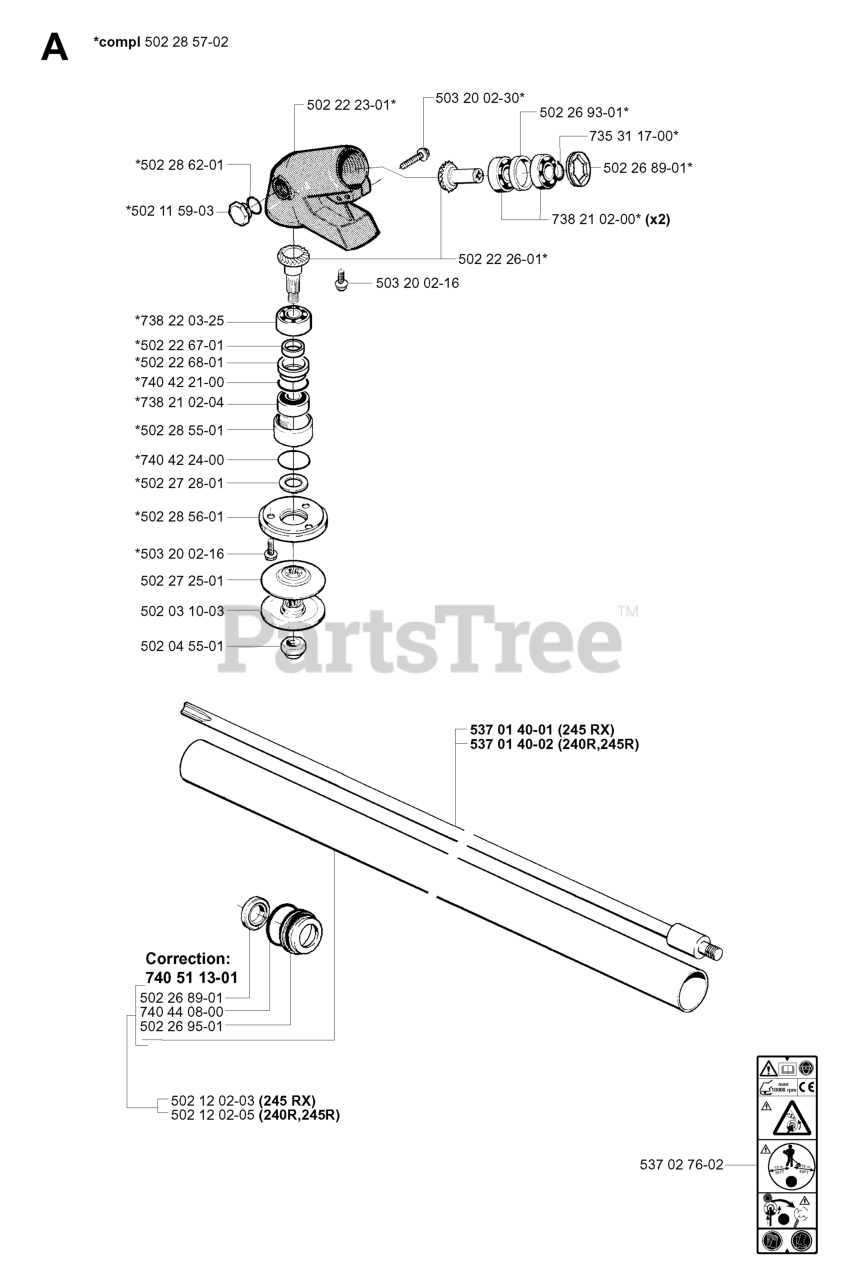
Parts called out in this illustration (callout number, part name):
1	Battery 12 Volt 25 Amp
2	BOLT.HEX.1/4.X.3/4.DICHROMATE
8	TRAY.BATTERY BOX.FRONT
16	SWITCH INTERLOOK PUSH-IN
21	HARNESS.LIGHT W/4152J BULBS
24	CABLE.BATT.POS.WIRE.TG.DA SOL
25	CABLE.STARTER.6G.BL/RED.17.5
26	FUSE 20AMP
27	NUT
28	CABLE GROUND 6 GA 21" 90T BLK
29	SWITCH.SEAT.DELTA.OPC.
30	SWITCH.IGN.DELTA.W.LGH.ROS
33	KEY.CHAIN.BLISTER.PACK.GEN.USA
40	HARNESS.IGN.DASH.HUSQ/PRED.
41	SCREW
42	TERMINAL COVER
43	SOLENOID.W/BRASS.PLUNGER
46	RP.GUAGE.SRVCMNDR.HRMTR.
50	RP.PTO.SWITCH.8 TERMINAL.BLACK
55	SCREW 5/16"
59	OUTLET.12-VOLT
71	HARNESS.IGN.CHASSIS.TEX.DCKLOC
75	SWITCH.ON/OFF.(DIFF.LOCK)
79	BULB HOLDER ASM.
90	COVER.TERMINAL.BATTERY
99	SCREW HEXWSHR 1/4-20X3/4
102	HARNESS PIGTAIL PCH TEX ROS
103	HARNESS PIGTAIL 12V OUTLET
105	REVERSE SWITCH
142	CHARGE.PORT.PIGTAIL HARNESS
143	CHARGE.PORT
